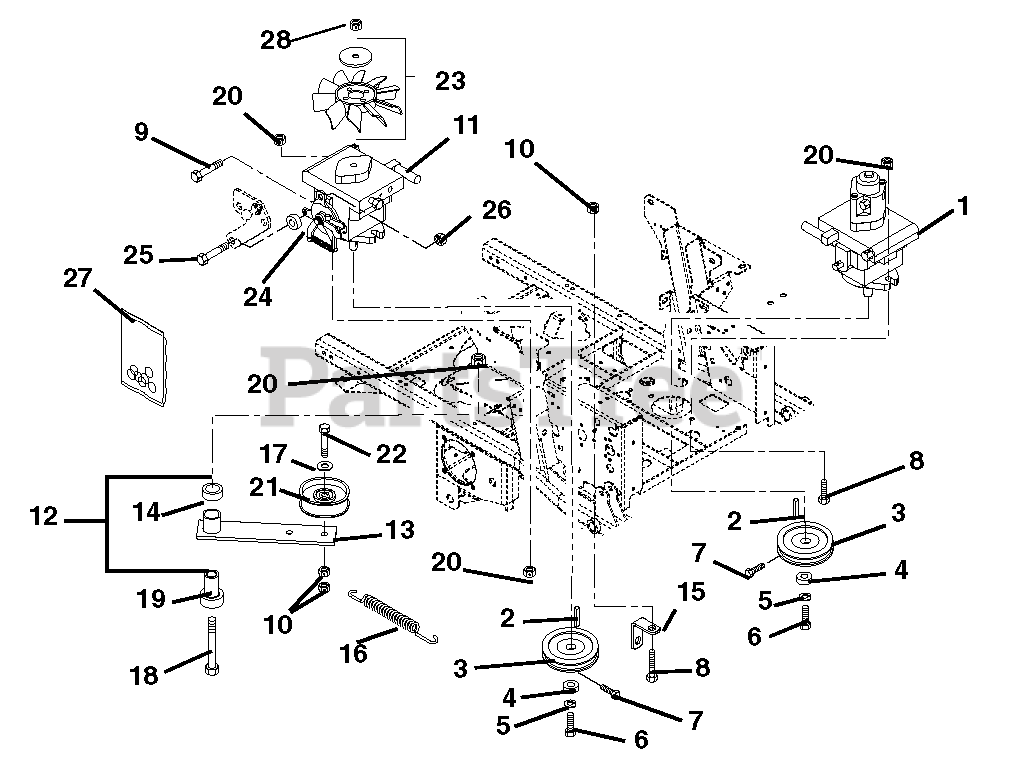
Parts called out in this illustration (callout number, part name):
1	Pump, Hydraulic with Auxiliary (189, 190, 192, 193)
2	Key, Square 5 x 5 x 30mm Plain
3	Sheave, Poly V .671 x 4.125
4	Washer, Flat Steel .281 x 1.000 x .063
5	Washer, Locking .25 x .062
6	Bolt, Hex M6 x 1.0 x 16
7	Screw, Socket Head .25-20 x .50 YZ EP80
8	Bolt, Hex .50-13 x 1.50 Grade 5
9	Bolt, Hex .31-18 x .75 Grade 5
10	Nut-Locking-Top-Flange .38-16
11	Pump, Hydraulic BDP-21 with Thru Fan
12	Assembly, Idler Arm Guard Drive (Includes 13 & 14)
13	Weldment, Idler Arm Ground Drive
14	Bushing, 1.00 x 1.125 x 1.936
15	Anchor, Spring Idler
16	Spring, Tension
17	Washer, Flat Steel .39 x .75 x.125
18	Bolt, Hex .50-13 x 3.50 Grade 5
19	Bearing, Pedestal
20	Nut, Locking Top Flange .50-13
21	Idler, Flay 4.00 x .38
22	Bolt, Hex .38-16 x 2.25 Grade 5
23	Fan, Hydro Pump Cooling
24	Spacer .318 x .43 x .375
25	Bolt, Hex .31-18 x 1.25 Grade 5
26	Nut, Locking Top Flange .31-18
27	Kit, Pump Seal (BDP-21A)(One kit required for each pump)
28	Nut, Center-Lock .31-24
